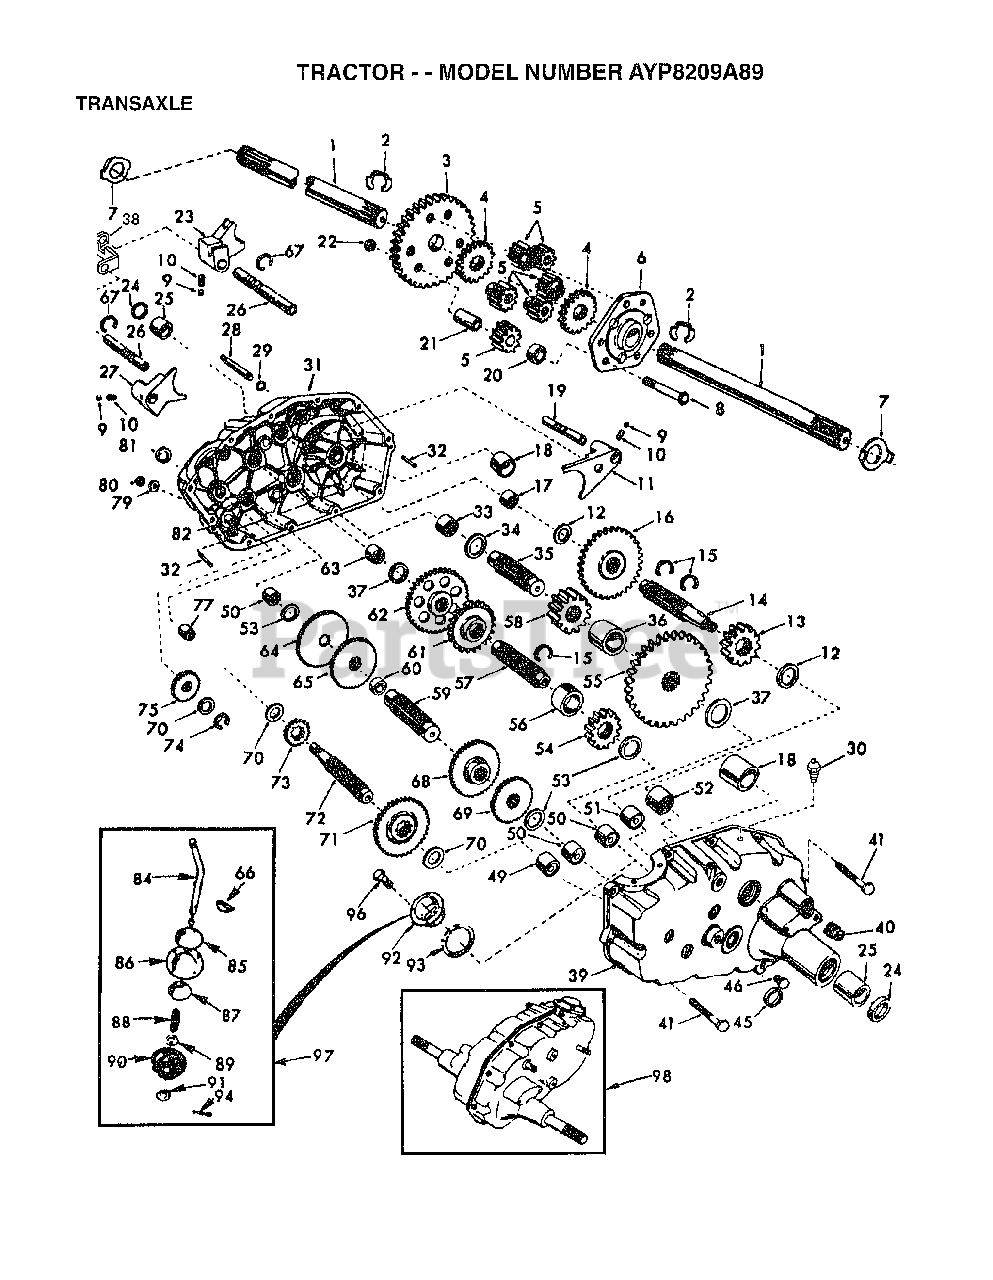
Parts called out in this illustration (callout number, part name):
1	SHAFT.AXLE.T
2	KLIP RING
3	FINAL GEAR T
4	DIFF GEAR T
5	DIFF PINION T
6	DIFF CARRIER T
8	BOLT
11	SHIFT FORK T
12	WASHER .T
13	RED PINION T
14	SHAFT BRAKE GT
15	SNAP RING T
16	GEAR T
17	"T, BEARING"
18	BEARING
19	SHAFT
20	SPACER T
21	PINION RS
22	GRIPCO NUT
23	FORK T
24	OIL SEAL STD
25	BRNG. T
26	SHIFT FORK SHAFT
27	SHIFT FORK T
28	SHIFT SHAFT
29	SEAL T
30	VALVE M
31	GEARCASE RH W/BER
32	PIN T
33	NEEDLE BRNG T
34	RACE T
35	GEAR SHAFT T
37	RACE T
38	GAT.LOWE.SHIFT.VGT
39	GEARCASE LH W/BER
40	PLUG PIPE
41	BOLT.5/16-18X1.25
45	SEAL T
49	"TI, BEARING"
50	NEEDLE BRNG T
51	NEEDLE BRNG T
52	"STD, BEARING"
53	BRNG RACE
54	RED PINION T
55	RED GEAR T
56	PINION SPACER T
57	GEAR SHAFT T
58	FINAL PINION T
59	GEAR SHAFT T
60	SPACER T
61	RED PINION T
62	RED GEAR T
63	RACE T
64	LOW SPEED GEA T
65	REVERSE GEAR T
66	KEY T
67	KLIP RING
68	INTERMED GEAR T
70	"T, BEARING"
71	CLUSTER GEAR T
72	SHAFT INPUT
73	LO SPEED PINION T
74	KLIP RING
75	IDLER GEAR T
77	NEEDLE BEARING TI
79	WASHER T
80	NUT
81	SEAL STD
82	SHAFT REVERSE IDL
84	GEAR SHIFT LVR T
85	CAP T
86	COVER AND PIN T
87	GUIDE BALL T
88	SPRING TI
89	WASHER
90	SEAL T
91	WASHER
92	GEAR SHIFT GA T
93	GASKET T
94	COTTER PIN
96	BOLT
97	GEAR SHFT LVR T
99	GAT.LOWE.SHIFT.VGT
